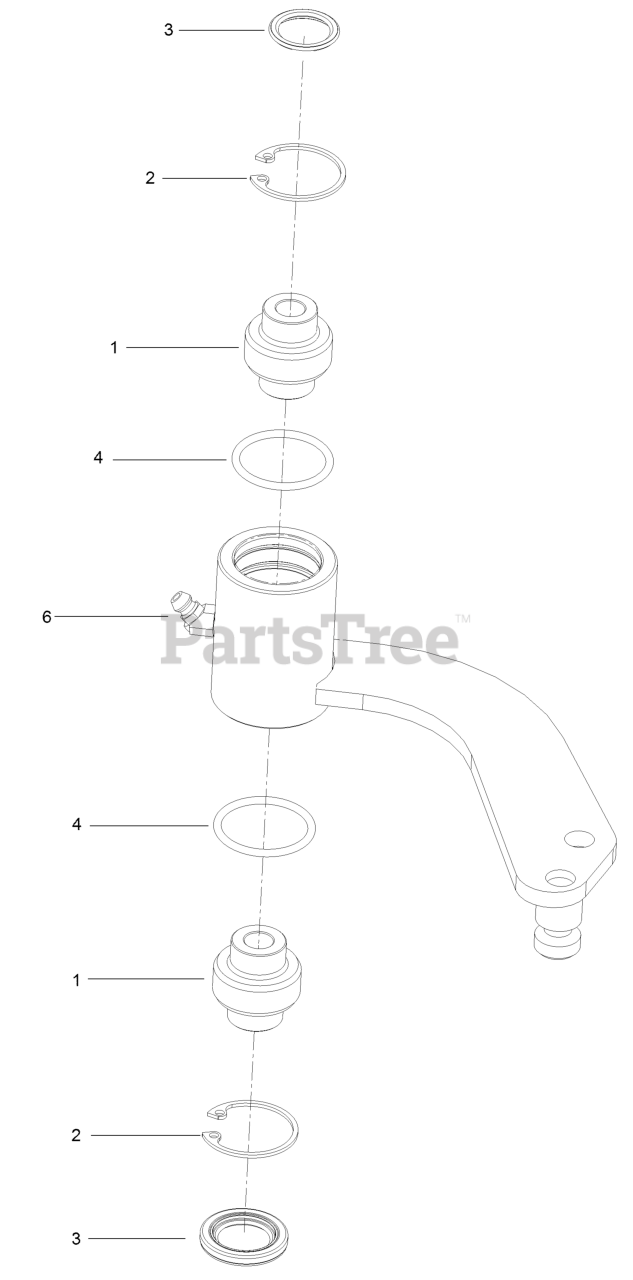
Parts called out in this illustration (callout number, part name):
1	BEARING-SPHERICAL
2	RING-SNAP
3	SEAL-LIP, SINGLE
6	FITTING-LUBE, 45 DEG
